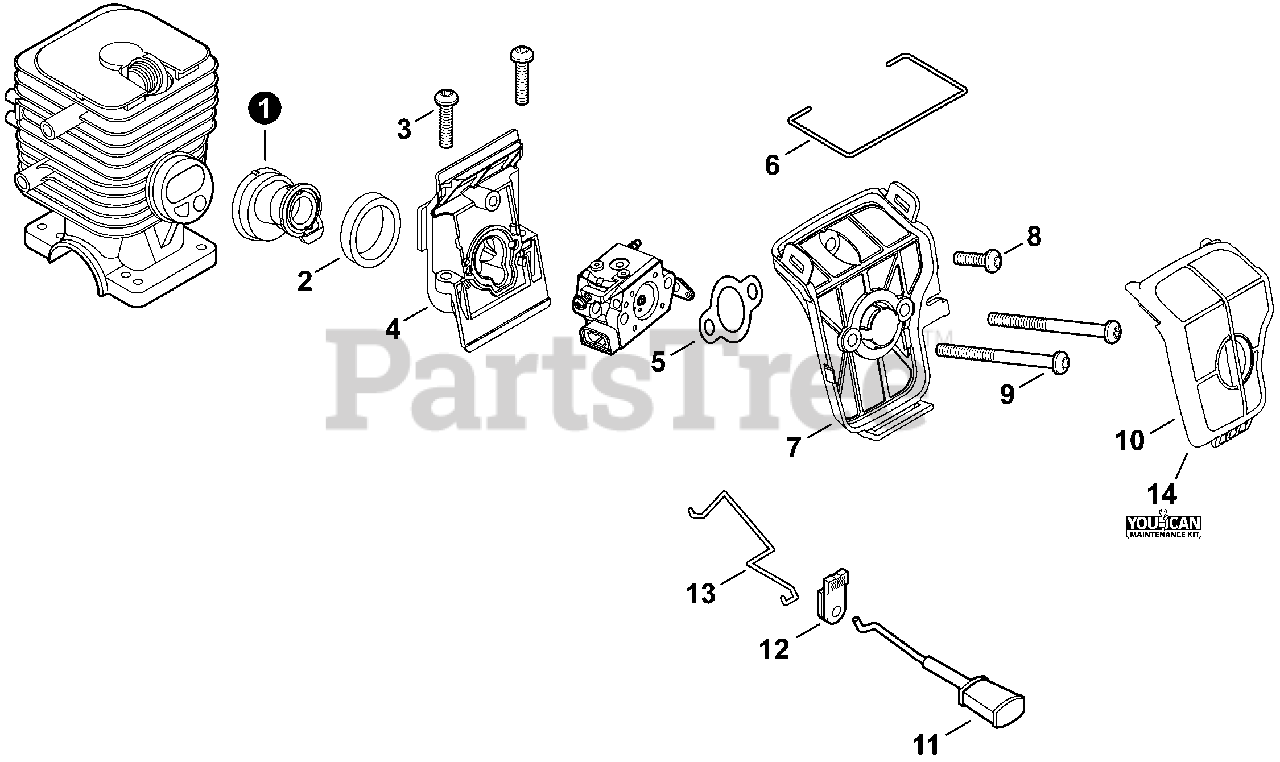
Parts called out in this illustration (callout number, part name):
1	BELLOWS, INTAKE
2	RETAINER, BELLOWS
3	BOLT, TORX 5×20
4	INSULATOR, INTAKE
5	GASKET, INTAKE
6	RETAINER, AIR FILTER
7	CASE, AIR FILTER
8	BOLT, TORX 5×16
9	BOLT, TORX 5×55
10	FILTER, AIR
11	ROD, CHOKE
12	GROMMET, CHOKE
13	ROD, THROTTLE
14	TUNE-UP KIT - YOUCANT
